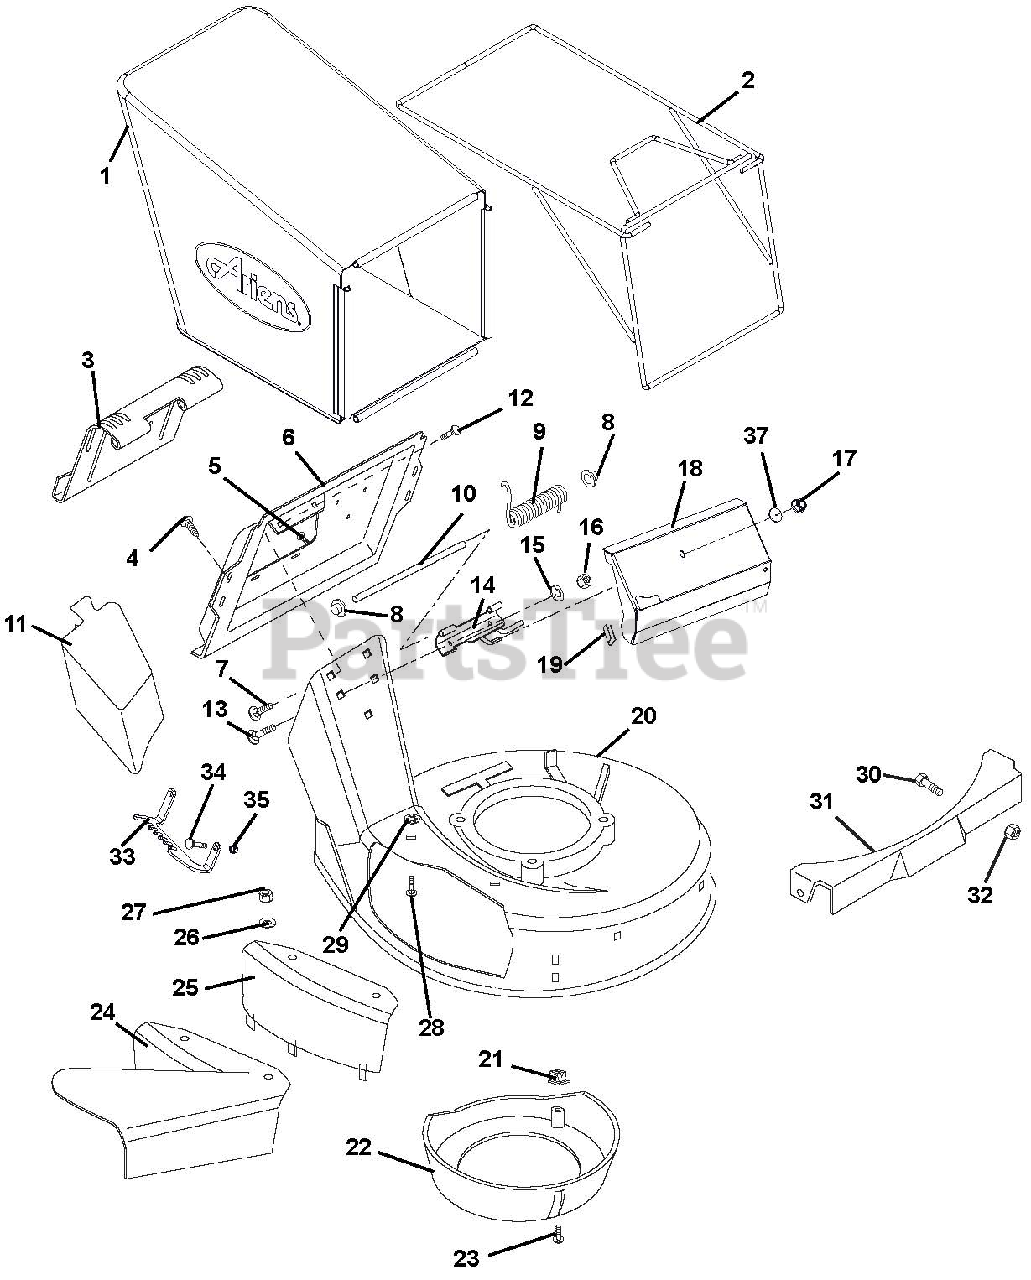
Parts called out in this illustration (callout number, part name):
1	BAGGER, ARIENS LM
2	FRAME, BAGGER
3	CATCHER PLATE DOOR
4	@SCR-TAP 12-24X.50 HWH TR YWZC
5	SCR-TAP 10-24X.375 TORX PHD YZ
6	CATCHER PLATE
7	@BLT-RHDSSQNK .25-20X.38 G2YZ
8	PUSH NUT, .25
9	SG-TORS .120X.68X3.09
10	DOOR PIN
11	MULCH MASTER PLUG
12	@NUT-SPNLK-FLG .25-20 YWZC
13	@BLT-RDHDSQNK .25-20X.75 G5YZ
14	HINGE BASE WELDMENT
15	WSHR-LK .250X.077 HVY YWZC
16	@NUT-HEX .25-20 YWZC
17	@NUT-LK-NYL-FLG .25-20 YWZC
18	COVER, LM BRIGGS CE DRIVE
18	COVER, LM DRIVE
19	TRIM BUMPER
20	MOWER PAN HEAD W/SFTYDECALS SP
21	PLASTIC GROMMET
22	CENTER BAFFLE
23	SCR-TAP 10-16X.62 SLPH AB YWZC
24	SIDE DISCHARGE ASSEMBLY
25	COVER, SIDE DISCHARGE
26	@WSHR-FL-STL.406X.812X.065 YWZ
27	@NUT-LK-NYL .312-18 YWZC
28	@BLT-RHDSSQNK .31-18X.75 G5YZ
28	@BLT-RDHDSQNK .31-18X.75 G5YZ
29	NUT-PUSH .312
30	@BLT-RDHDSQNK .31-18X.50 G5YZ
31	PANEL-FRONT
32	@NUT-LK-TOP-FLG .31-18 YWZC
33	BRKT, SPD SELECTION
34	@BLT-RDHDSQNK .25-20X.50 G5YZ
35	@NUT-LK-CTR .25-20 YWZC
36	@WSHR-FL-STL.281X.62X.065 YWZC
37	WSHR-FL-NY .375X.75X.060
